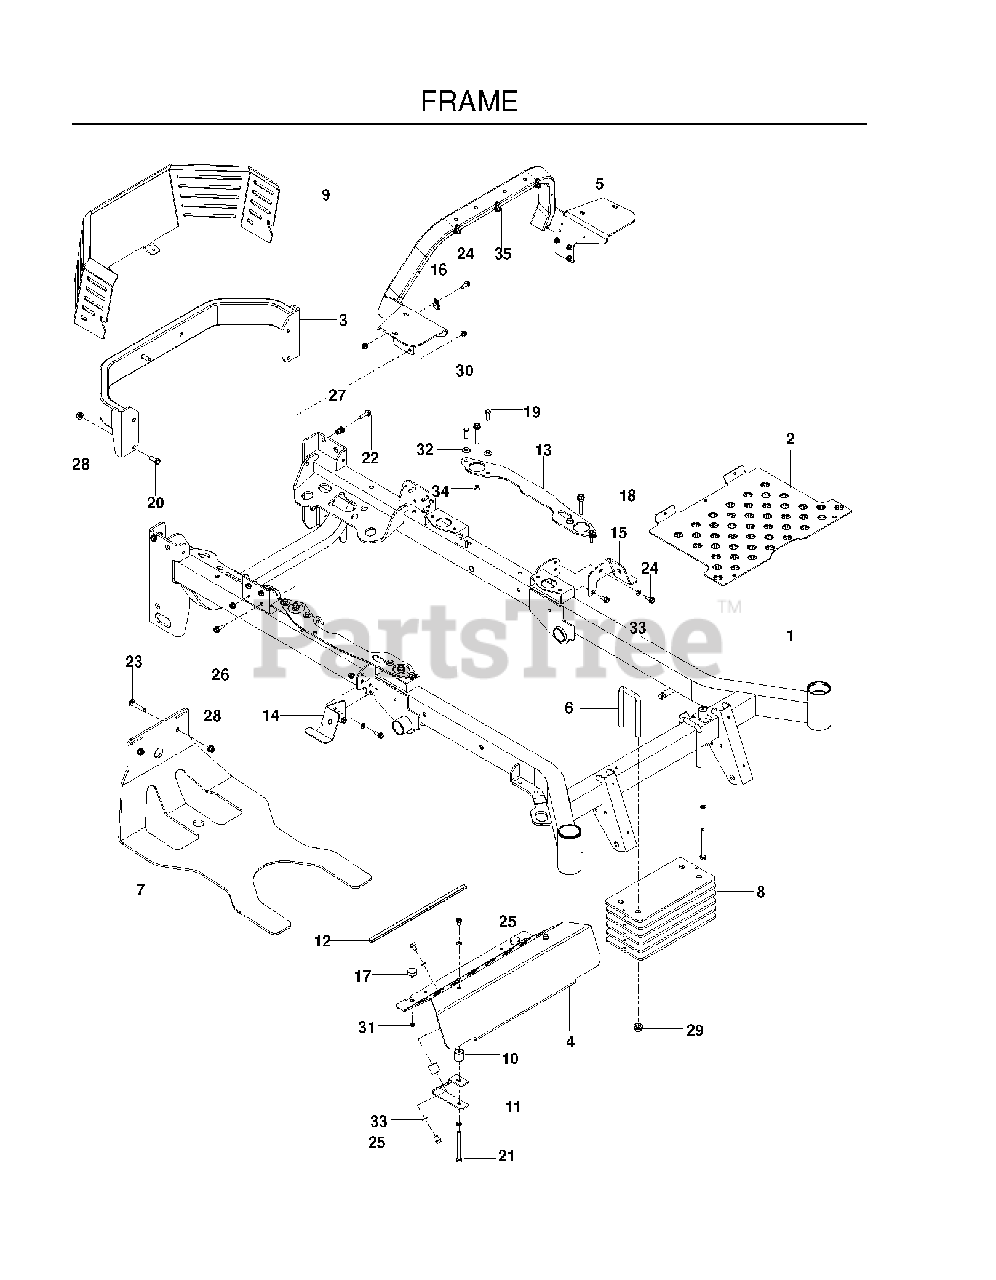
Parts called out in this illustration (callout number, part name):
1	FRAME, DIESEL, BLUE
2	PLATE, FLOOR PAN, BLUE
4	PLATE, FOOTREST, BLUE
6	LINKAGE, U-BOLT
8	PLATE, WEIGHT BLK
10	MOUNT, F/F INSERT
11	BRACKET, REST MOUNT
12	FLEX TRIM, BLACK
14	MOUNT, TANK, RT-BLK
15	MOUNT, TANK, LT-BLK
16	DOUBLE TUBE CLAMP
17	BUMPER, 1/4-20 STUD, 1/4
18	HHFS 3/8-16 X 2-1/4 GR 5 ZD
19	HCS 5/16C X 1
20	HCS 3/8C X 1
21	HHFS 5/16-18 X 3 3/4
22	HHFS 5/16-18 X 1.25 TPBLT GD 5
23	RHSNB 3/8C X 2
24	HHFS 5/16-18 X 3/4
25	SCR 5/16-18 X 1/2 SELFTAP ZN
26	BLT 5/16-18 X 1 THRD FORM ZD
27	NUTSERT 5/16-18 THICK GRIP
28	NUT 3/8-16 HEX FLG NYLOC ZD
29	NUT, 1/2-13 HEX FLG NYLOC ZD
30	5/16-18 NYLOC FLANGE NUT
31	JAM NUT 1/4C
32	WASHER 5/16 FLAT
33	WASH 5/16 DISC SPRING ZD
34	WASHER 3/8 X 3/4 X .187 TK
35	TIE WRAP, 8-3/8", W/CLIP
